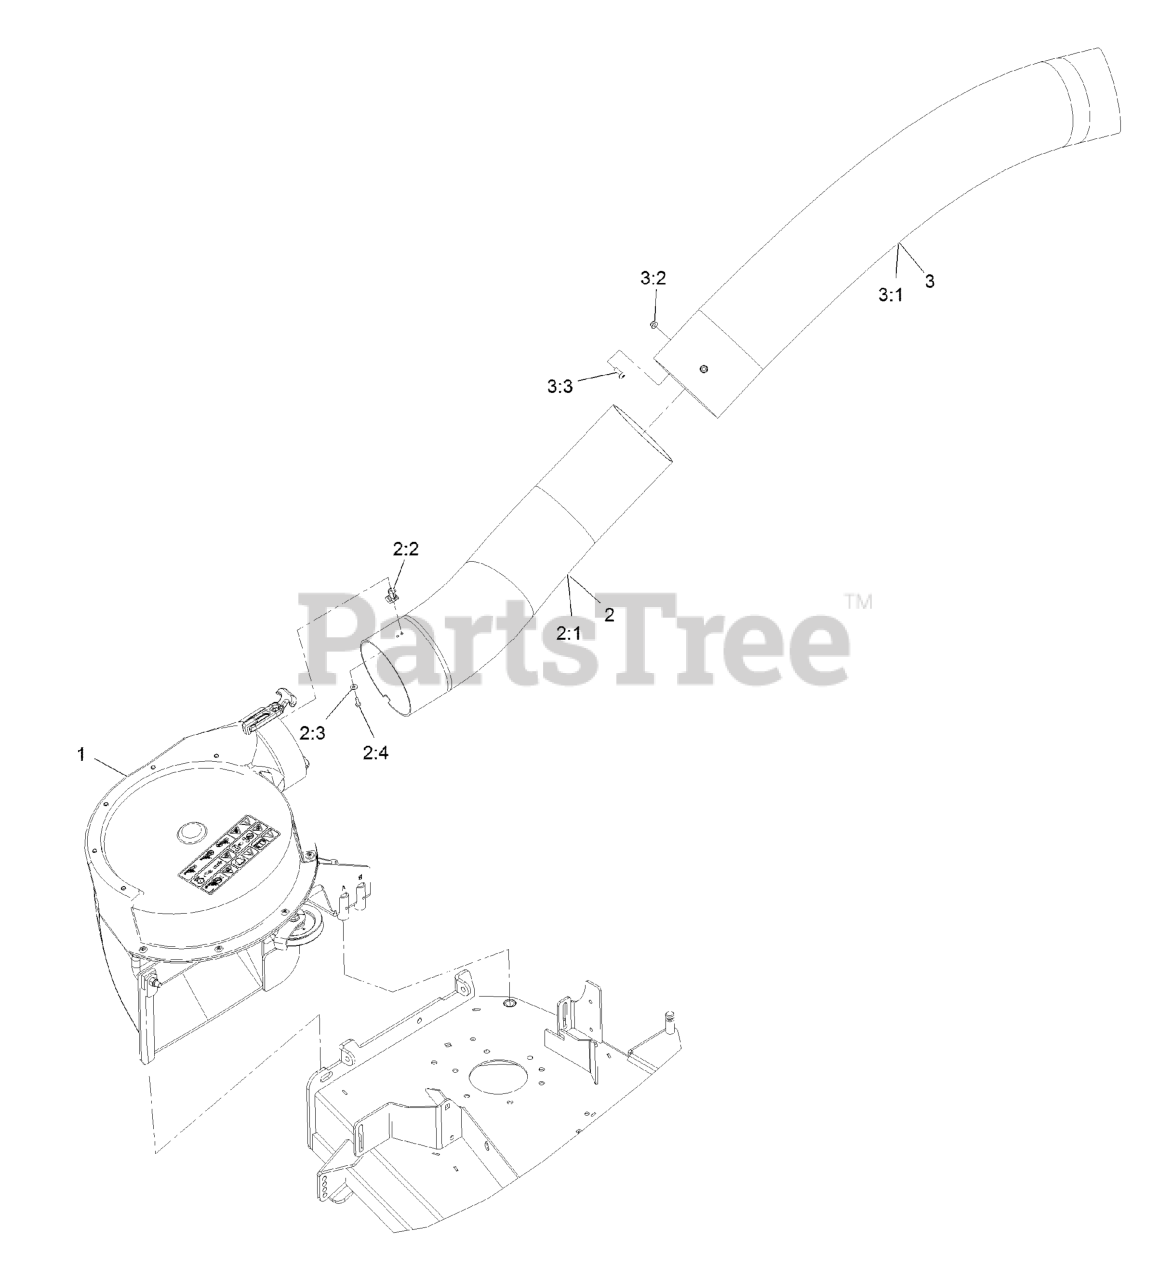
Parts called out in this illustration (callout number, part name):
1	ASM-BLOWER POWERED
2	LOWER TUBE ASM
2:1	TUBE-LOWER
2:2	LATCH-KEEPER
2:3	WASHER-FLAT
2:4	SCREW-PPH
3	UPPER TUBE ASM
3:1	TUBE-UPPER
